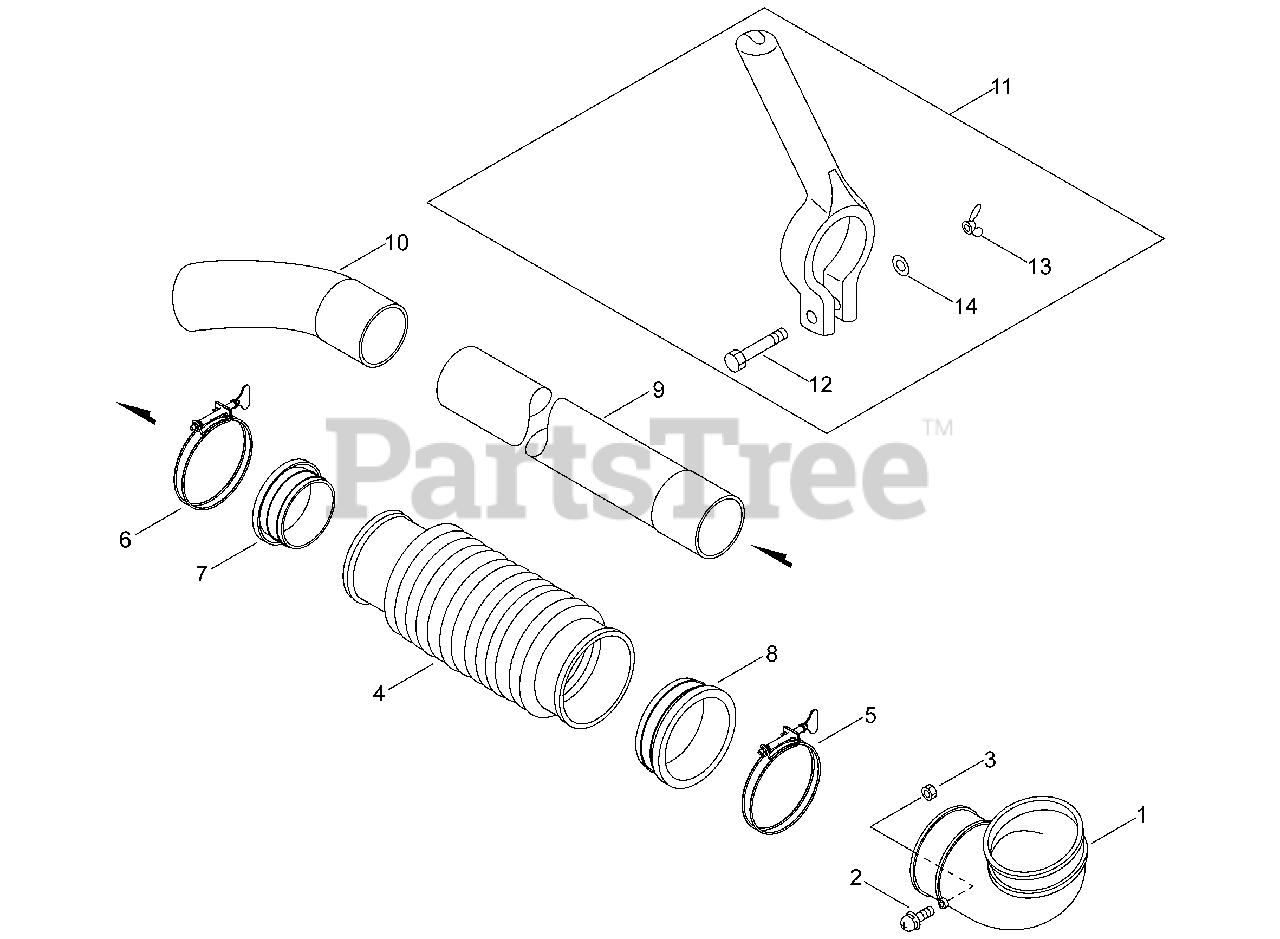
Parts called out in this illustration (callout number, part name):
1	TUBE, BLOWER - ELBOW
2	SCREW 5×14
3	NUT M5
4	TUBE, FLEXIBLE
5	CLAMP Ø95-Ø105
6	CLAMP Ø75-Ø85
9	TUBE, BLOWER - STRAIGHT
10	TUBE, BLOWER - CURVED
11	HANDLE, FRONT
12	BOLT 6×45
13	NUT, WING 6
14	WASHER 6.5×11.5×0.8
